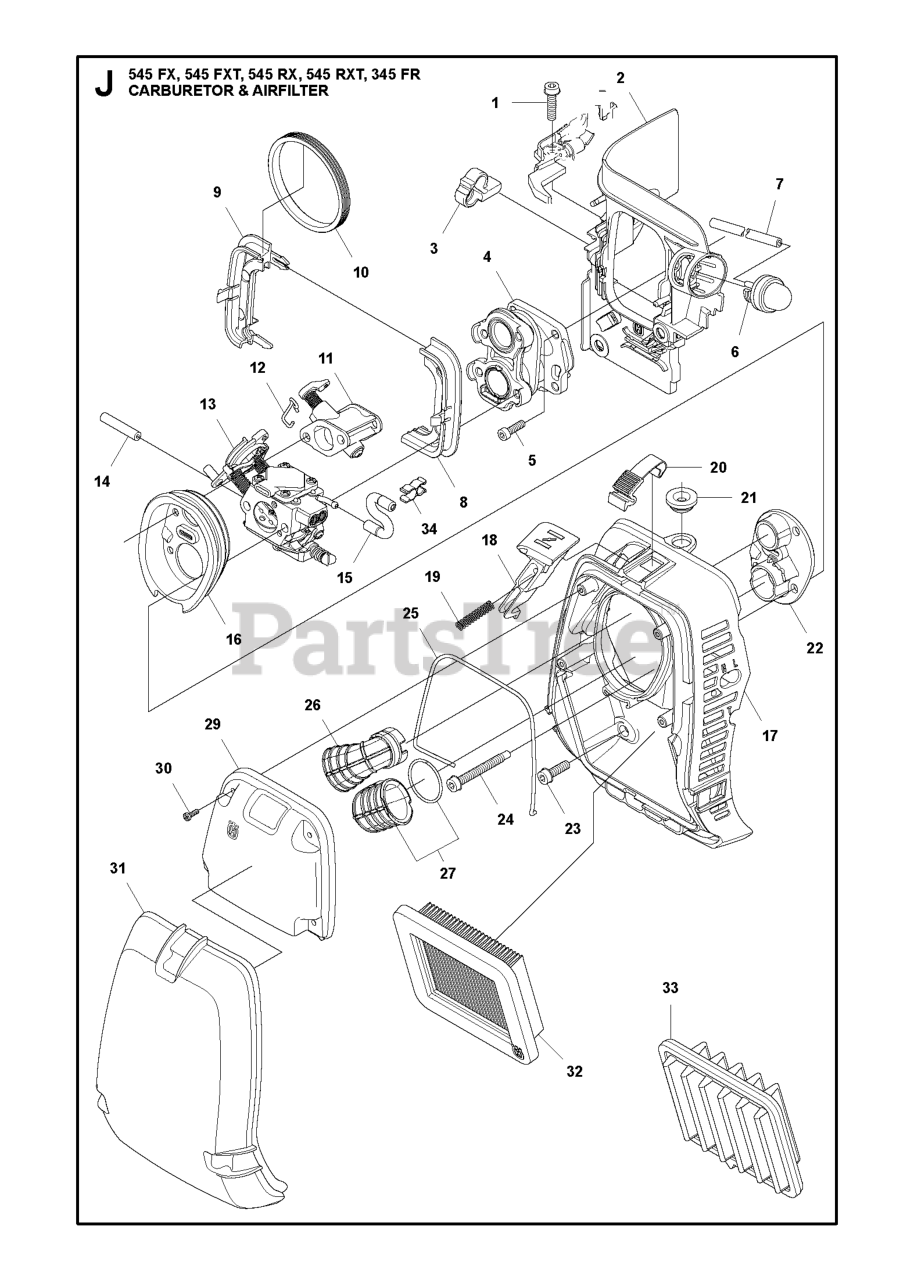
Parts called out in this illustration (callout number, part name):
2	INSULATION WALL
4	INLET PIPE
6	AIR PURGE BUBBLE
10	SEALING RING
13	CARBURETOR
14	FUEL HOSE STRAIGHT 38
17	FILTER HOLDER ASSY
18	CHOKE CONTROL
22	COVER PLATE
23	SCREW IHSCFM
26	INLET PIPE AIR HEAD
29	COVER LID ASSY
31	FILTER COVER
32	FILTER AIR FILTER PAPER
33	Filters
